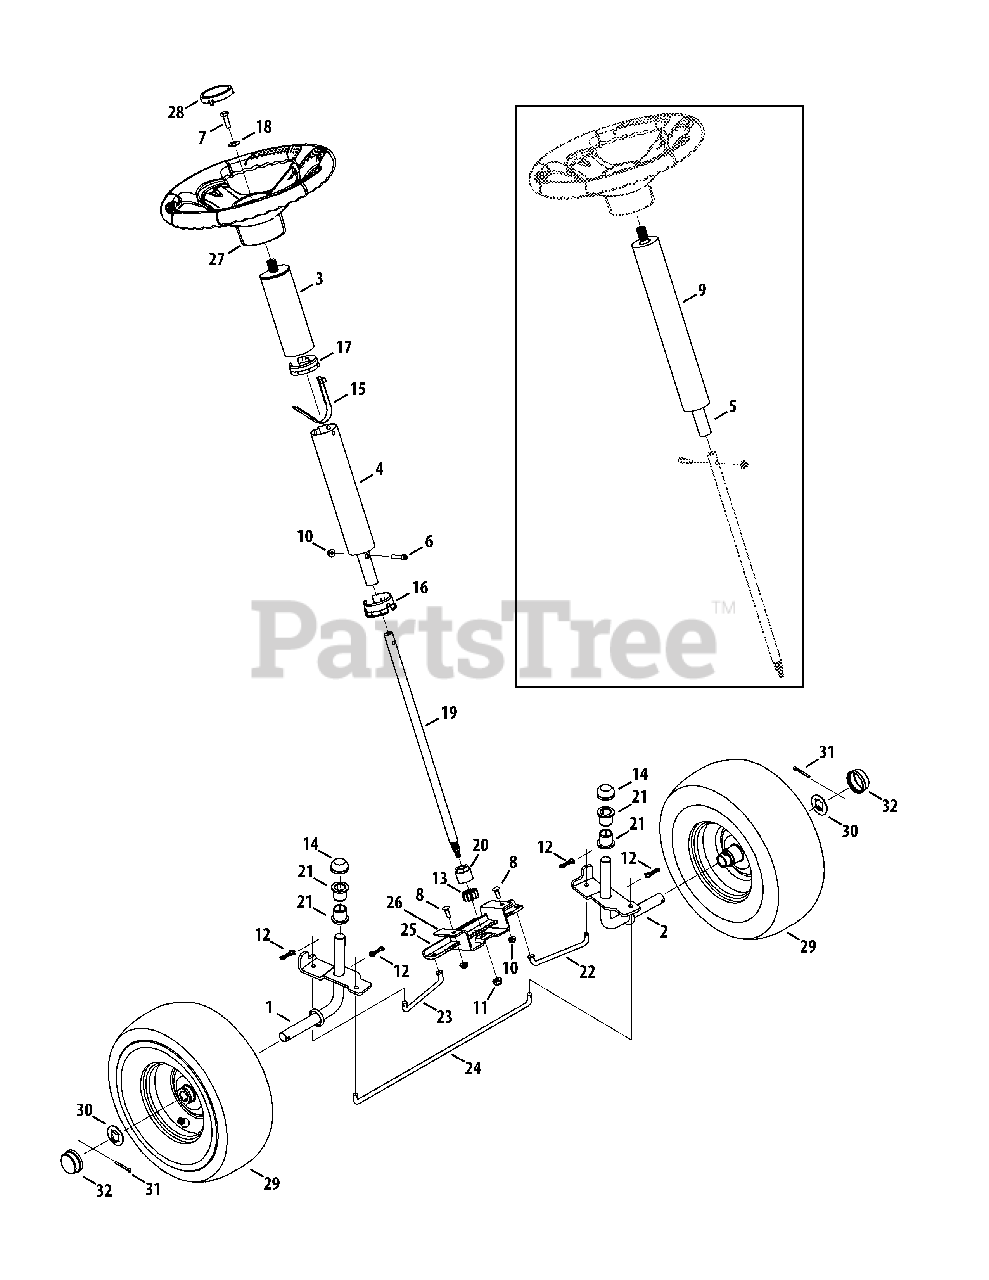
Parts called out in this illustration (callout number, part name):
1	Front Axle Assembly, RH
2	Front Axle Assembly, LH
3	Upper Tube Assembly
4	Lower Tube Assembly
5	Tube Assembly, Non-Telescoping
6	Shoulder Screw, .375 x .148 x 1/4-20
7	Hex Head Screw, 5/16-18:1.00
8	Carriage Screw, 1/4-20, .75
9	Steering Sleeve
10	Flange Lock Nut, 1/4-20
11	Flange Lock Nut, 5/16-18
12	Bow-Tie Cotter Pin, 72
13	Steering Pinion Gear
14	Push Cap, 3/4
15	Snap Butt
16	Lower Steering Collar
17	Upper Steering Collar
18	Bevel Washer, .340X.872X.060
19	Steering Shaft, .625 OD X 18.03
20	Hex Flange Bearing, 5/8
21	Flange Bearing, .760 X .941 X 1.0
22	Steering Rod, LH
23	Steering Rod, RH
24	Front Tie Rod
25	Steering Rack Plate
26	Lower Steering Bearing
27	Steering Wheel, Std. Grip
28	No Sprig Cap
29	Complete Wheel Assembly
30	Washer, .781 x 1.59
31	Cotter Pin, 5/32 x 1.25
32	Hub Cap
